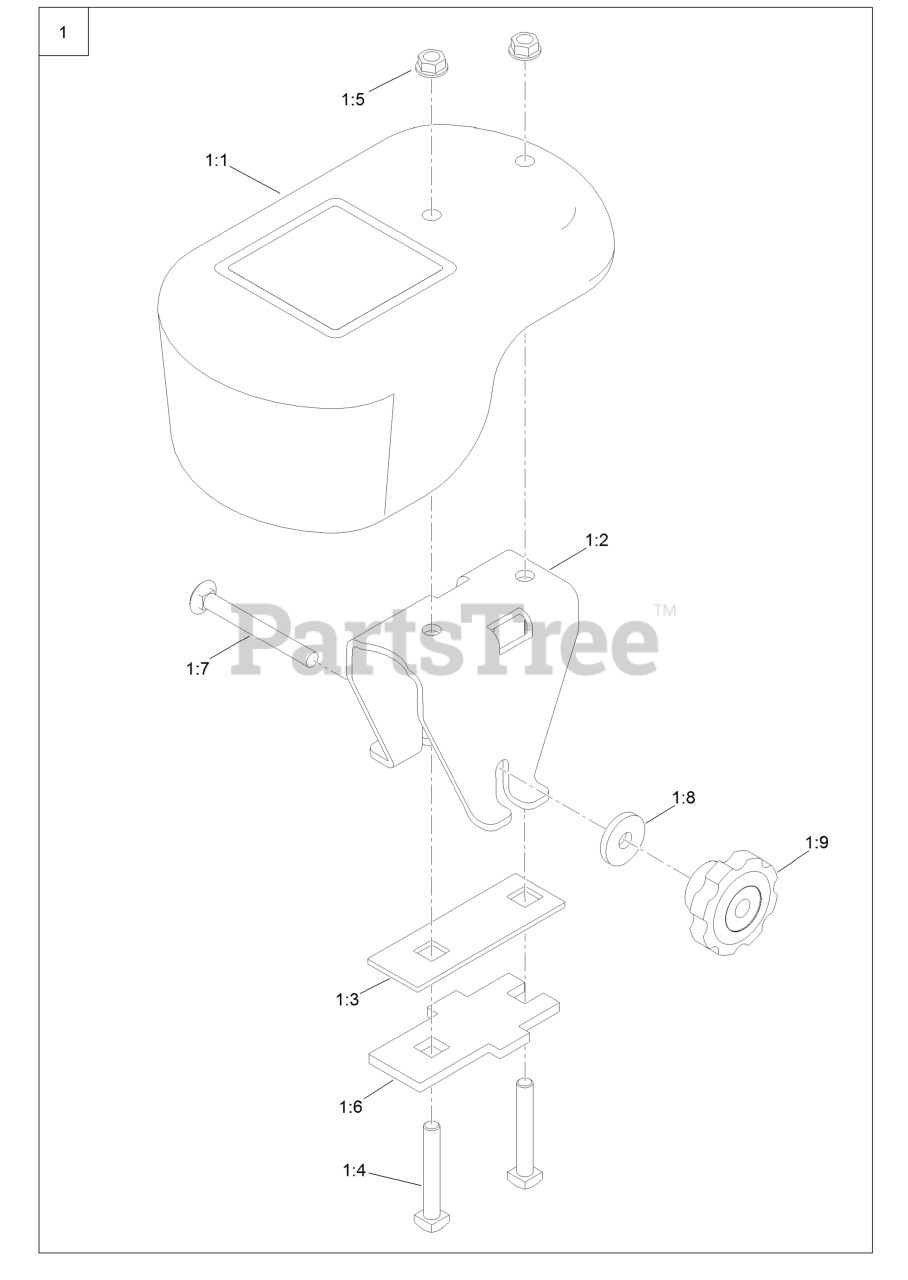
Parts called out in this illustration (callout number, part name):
1	CASTER WEIGHT ASM
1:1	WEIGHT WITH DECAL ASM
1:2	CHANNEL-MOUNT, WEIGHT
1:3	PLATE-BRACKET, WEIGHT
1:4	BOLT-SQH
1:5	NUT-HHF, WHIZ
1:6	PLATE-BRACKET, WEIGHT
1:7	SCREW-CARR
1:8	WASHER-BACKUP
